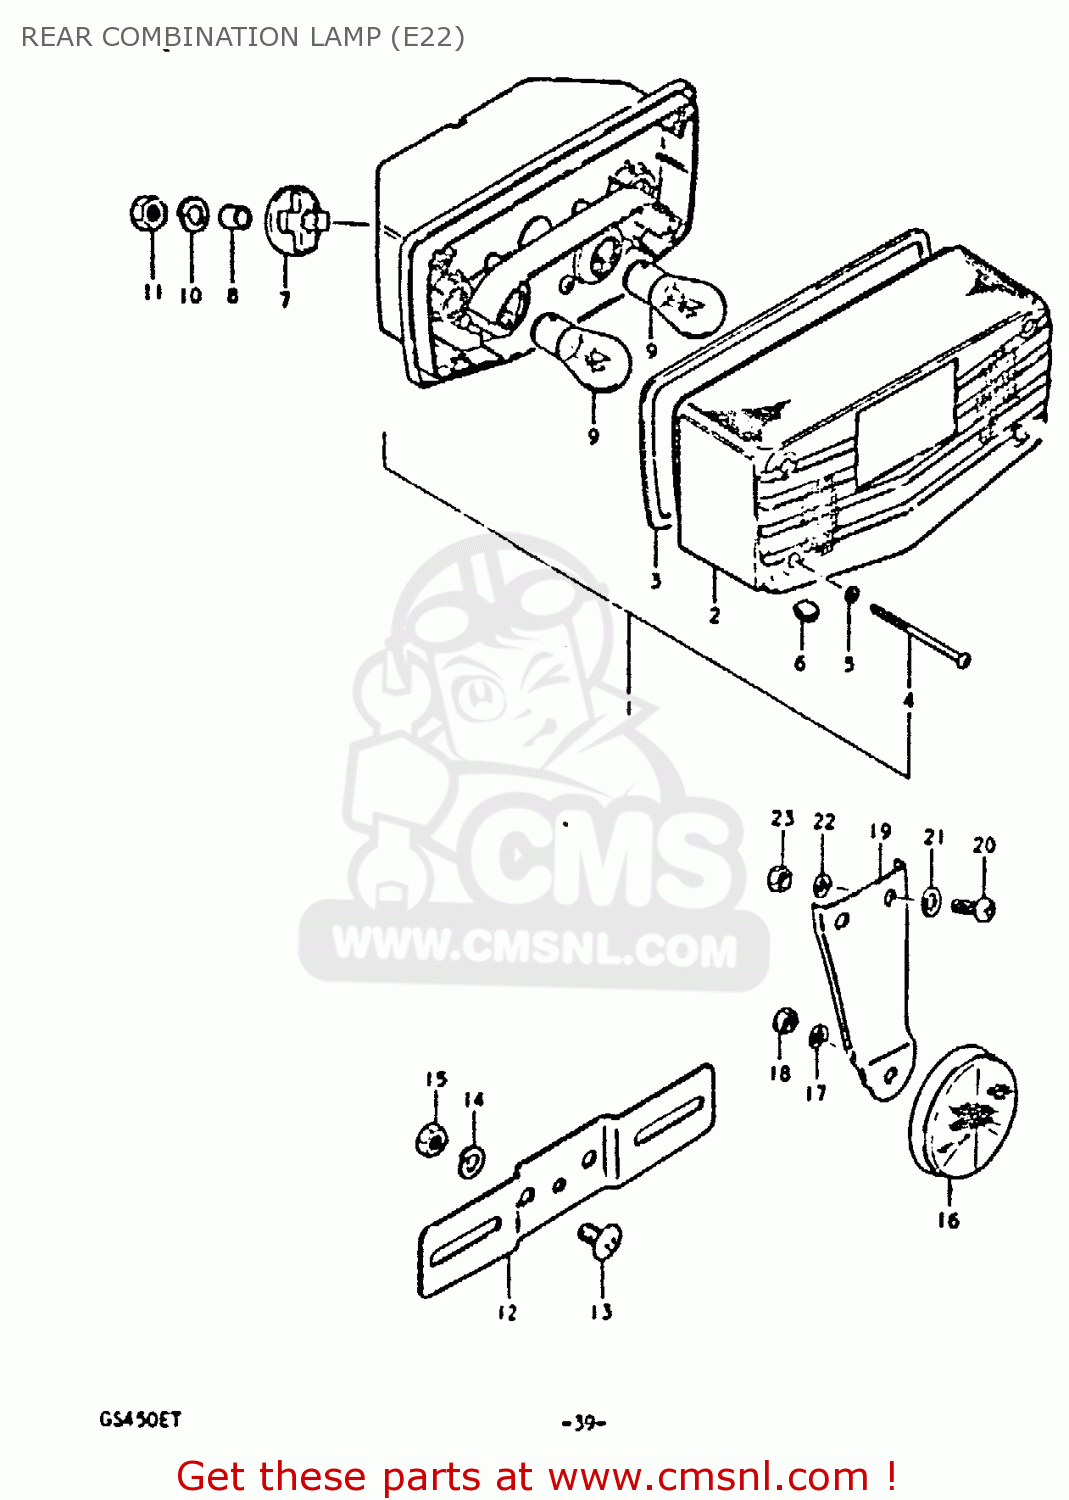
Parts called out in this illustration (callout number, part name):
1	LAMP ASSY, REAR COMBINATION
2	LENS
3	GASKET,REAR COMBINATION LAMP LENS (NAS)
4	SCREW
5	GASKET (NAS)
6	GROMMET,REAR COMBINATION LAMP
7	CUSHION,REAR COMBINATION LAMP
8	SPACER,REAR COMBINATION LAMP
9	BULB(12V21/5W)
10	LOCK WASHER
11	NUT
12	PLATE,RR LICENSE
13	SCREW
14	LOCK WASHER
15	NUT
16	REFLEX REFLECTOR,RR
17	LOCK WASHER
18	NUT
19	BRACKET
20	SCREW
21	WASHER
22	LOCK WASHER
23	NUT
